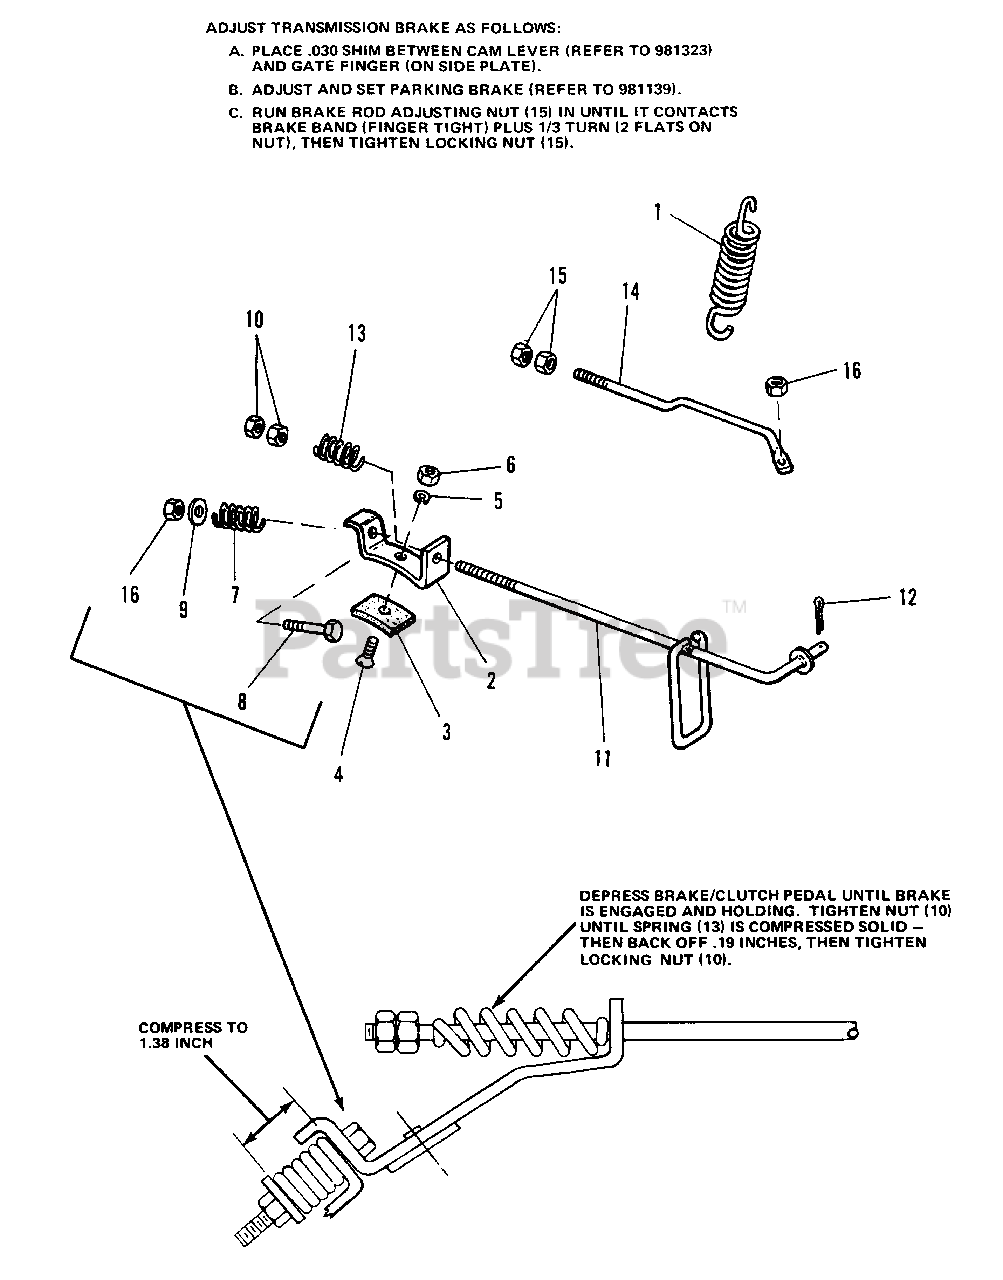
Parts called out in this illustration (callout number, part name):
2	STRAP, Pulley Brake
3	BRAKE, Sheave
4	SCREW, Machine, No. 10-24 x 5/8
5	LOCKWASHER, No. 10
6	NUT, Hex, full, No. 10-24
8	CAPSCREW, 5/16-18 x 2-1/4
9	WASHER, 1/4 Std.
10	NUT, Hex, Full, 5/16-18
11	PULLEY BRAKE ROD ASSEMBLY
12	PIN, Cotter, 3/32 x 1/2
14	ROD, Brake
15	NUT,Hex,Full, 3/8-16
16	LOCKNUT, Hex, 5/16-18
